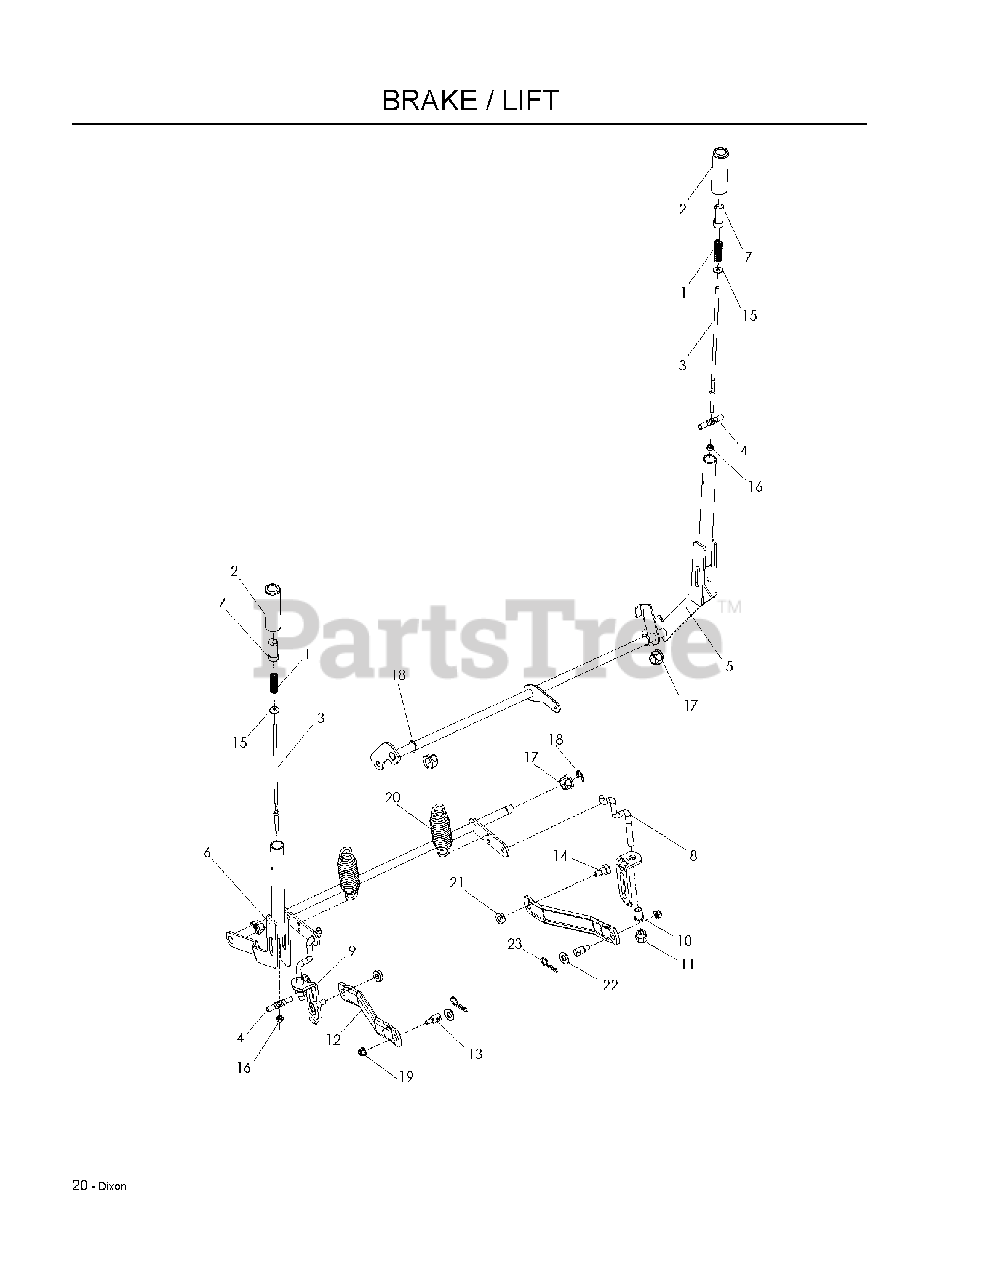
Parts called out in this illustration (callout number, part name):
1	SPRING, COMPRESSION
2	GRIP, HANDLE, BLACK
3	ROD, HANDLE RELEASE
4	ROD, LATCH RELEASE
5	SHAFT ASSY, BRAKE, MED, BLK
6	SHAFT, LIFT, MED BLK
7	BUTTON, PUSH, BLACK (2 2)
8	LINK, REAR SUSPENSION
9	BRACKET CONNECT LINK LIFT
10	BUSHING ALIGNMENT LINK LIFT
11	NUT, LIFT LINK 7/16-20
12	ARM.SUSPENSION.MOWER
13	STUD.FASTNER.W/ANTI-ROTATE
14	SB 3/8-16 X 3/8 SKT HD ZD
15	WASHER 1/4 FLAT
16	NUT 1/4-20 NYLOC
17	PLASTIC NUT
18	E-RING 5/8
19	5/16-18 NYLOC FLANGE NUT
22	WASHER 5/8 FLAT
23	HAIRPIN #4
